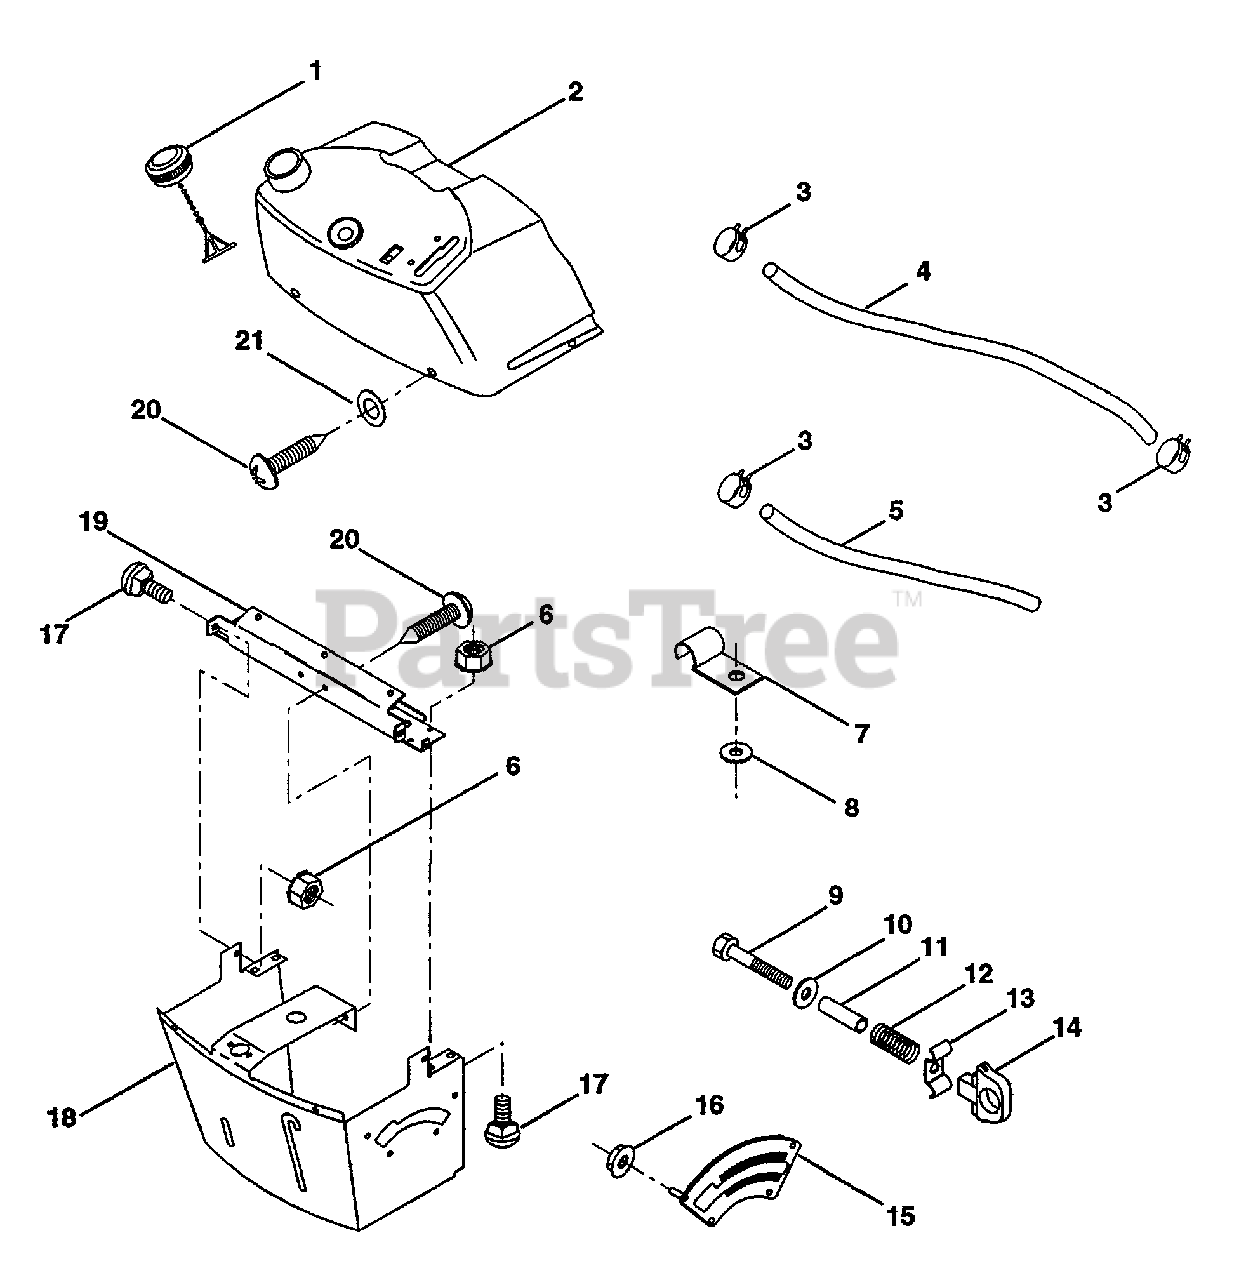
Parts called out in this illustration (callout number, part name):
1	Cap, Fuel
2	Assembly, Dash & Fuel Tank
3	Clamp, Hose
4	Line, Fuel
5	Line, Fuel
6	Nut, Hex, Keps 1/4-20
7	Clip, Fuel Line
8	Washer 9/32 x 3/4 x 16 Ga.
9	Bolt, Hex, Fin 1/4-20 x 1-3/4
10	Washer 11/32 x 11/16 x 16 Ga.
11	Spacer, Split
13	Clip, Height Adjustment
14	Knob, Height Stop
15	Adjustment, Quadrant Height
16	Nut, Self-Threading 3/16-18
17	Bolt, Carriage 1/4-20 x 1/2 Gr. 5
18	Support Assembly, Dash
19	Brace, Cross
20	Screw, Self-Tapping 1/4-20 x 1/2
21	Washer 9/32 x 1/2 x 16 Ga.
